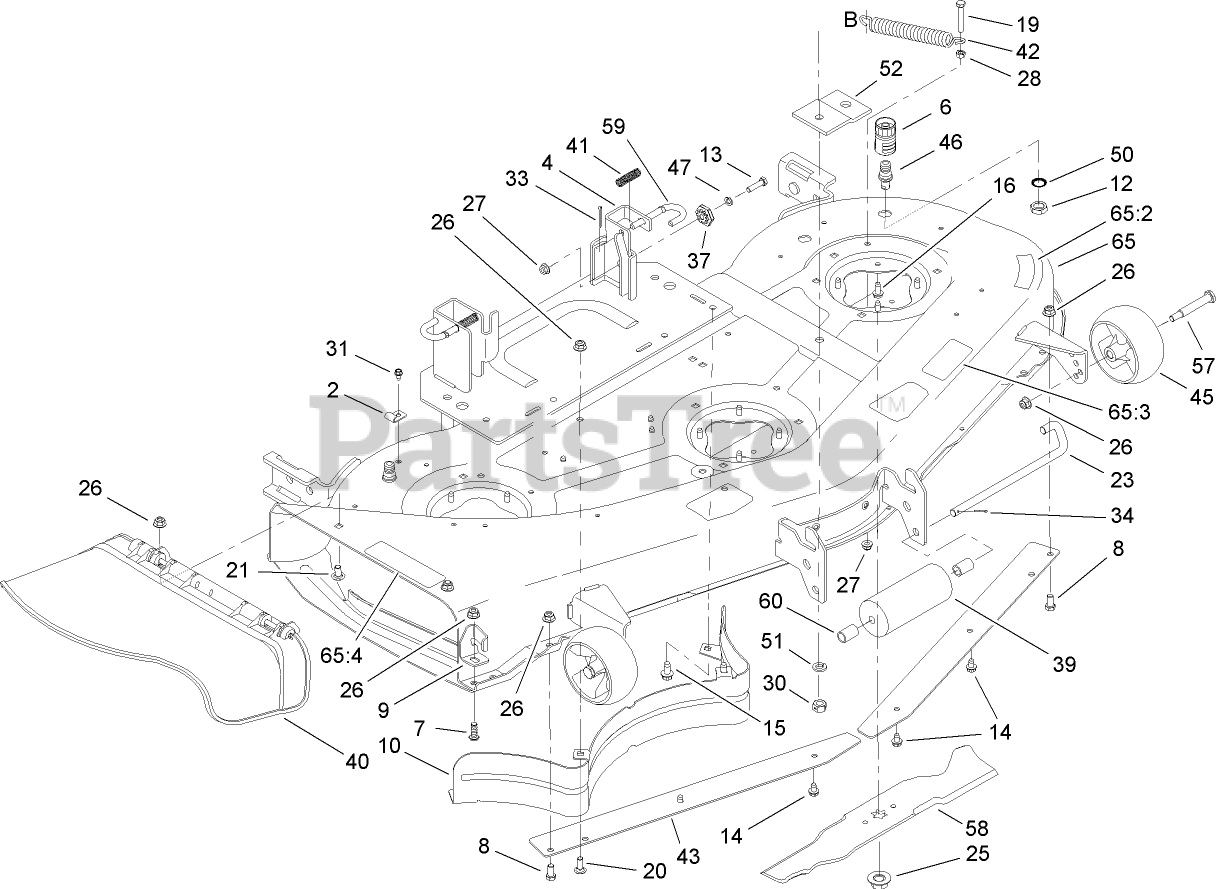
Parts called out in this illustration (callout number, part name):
2	BRACKET-RETAIN, HOOK
4	LH HANGER BRACKET ASM
6	ADAPTER-NOZZLE, WATER
7	SCREW-HH
8	SCREW-HH
9	STOP-CHUTE
10	BAFFLE
12	NUT-HEX
13	SCREW-HH
14	SCREW-TAP
15	SCREW-HWHTF
16	SCREW-HH
19	SCREW-HH
20	BOLT-CARR
21	BOLT-CARR
25	NUT-LOCK, FLANGE
26	NUT-LOCK, FLANGE
27	NUT-LOCK, FLANGE
28	NUT-HEX
30	NUT-HEX, LOCK
31	SCREW-HWHTF
33	PIN-COTTER
34	PIN-COTTER
37	GEAR-ADJUSTMENT, DECK
40	CHUTE DEFLECTOR ASM
41	SPRING-COMPRESSION
42	SPRING
43	SKIRT-DECK
45	WHEEL-DECK, FRONT
46	NOZZLE-WATER, DECK
47	WASHER-LOCK
50	WASHER-LOCK
51	WASHER-LOCK
52	BRACKET-STABILIZER
57	BOLT-SHOULDER
58	BLADE-18.50
59	PIN-HANDLE, DECK RELEASE
60	SPACER
65	DECK AND DECAL ASM
65:3	DECAL-BELT ROUTING, DECK
65:4	DECAL-DANGER
